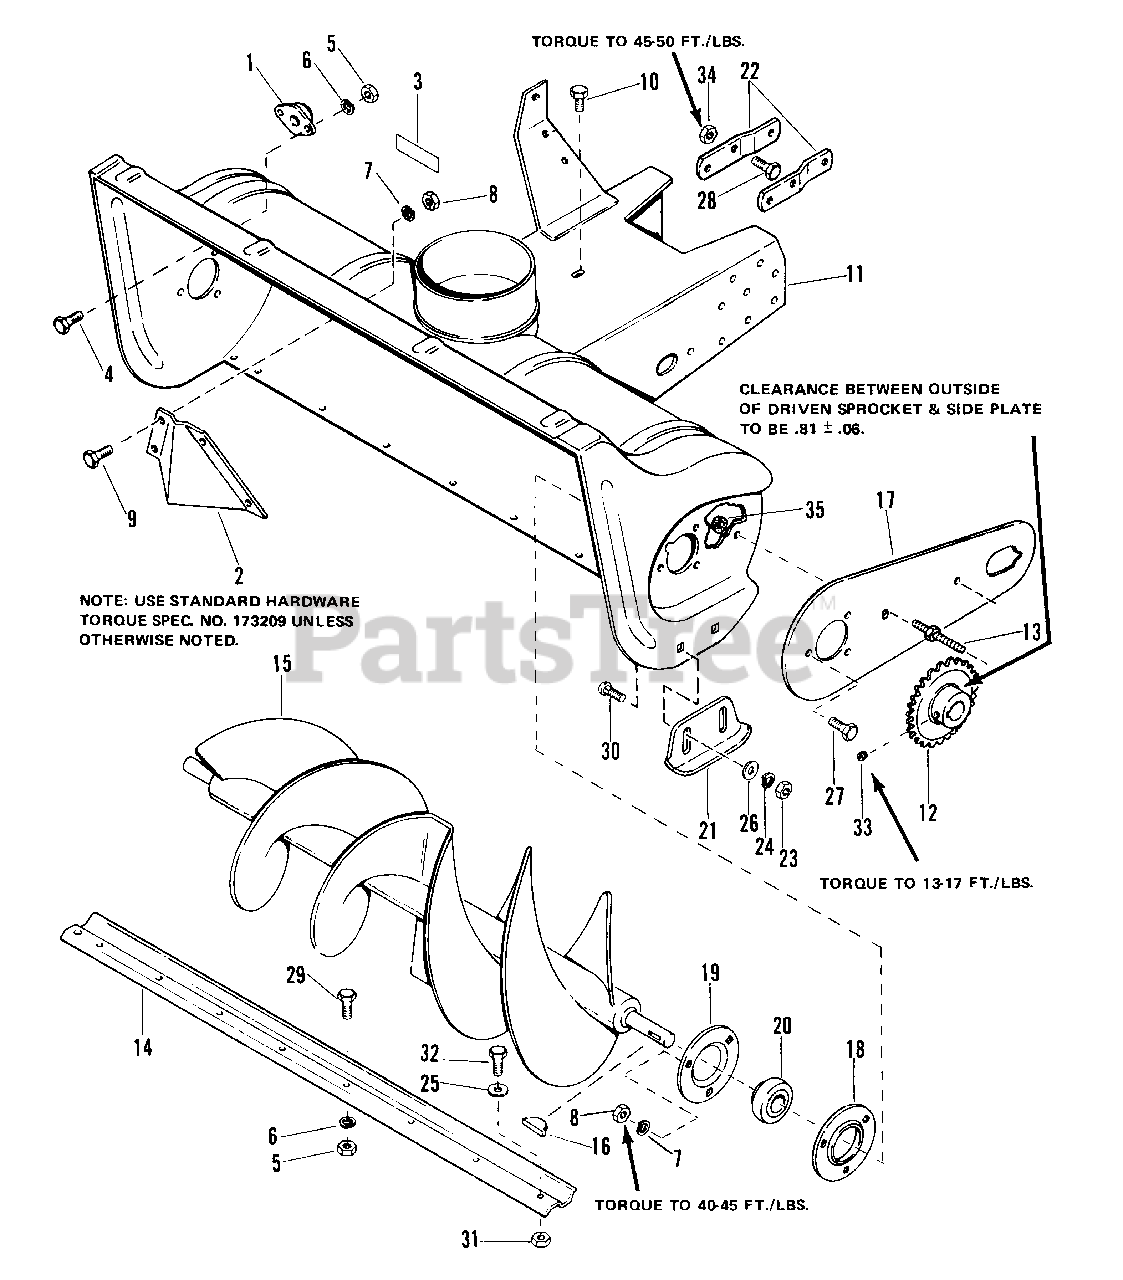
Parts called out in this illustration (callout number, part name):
3	DECAL, Safety
4	CAPSCREW, 1/4-20 x 5/8
5	NUT, Hex, 1/4-20
6	LOCKWASHER, 1/4
7	LOCKWASHER, 5/16
8	NUT, Hex, 5/16-18
9	CAPSCREW, Hex, 5/16-18 x 5/8
10	SCREW. Self-tapping, 5/16-18 x 1/2
11	BODY AND FRAME ASSEMBLY
14	SCRAPER, Body
16	KEY, Hi-pro
17	SIDE PLATE
18	FLANGE, Brg.
19	FLANGE, Brg., w/fitting
20	BEARING, Cartridge
22	CLIP, Frame
23	NUT, 3/8-16
24	LOCKWASHER, 3/8
25	WASHER, Plain, 1/4
26	WASHER, Plain, 3/8
27	CAPSCREW, Hex Hd., 5/16-18 x 3/4
28	CAPSCREW, Hex Hd., 7/16-14 x 1
29	CAPSCREW, Hex Hd., 1/4-20 x 5/8
30	BOLT, Carriage, 3/8-16 x 3/4
31	LOCKNUT, 5/16-18
32	CAPSCREW, Hex Hd., 5/16-18 x 5/8
33	SETSCREW. Skt. 5/16-18 x 5/16
34	NUT, Flange, 2-way Lock, 7/16-14
35	LOCKNUT, Flange, 3/8-16
